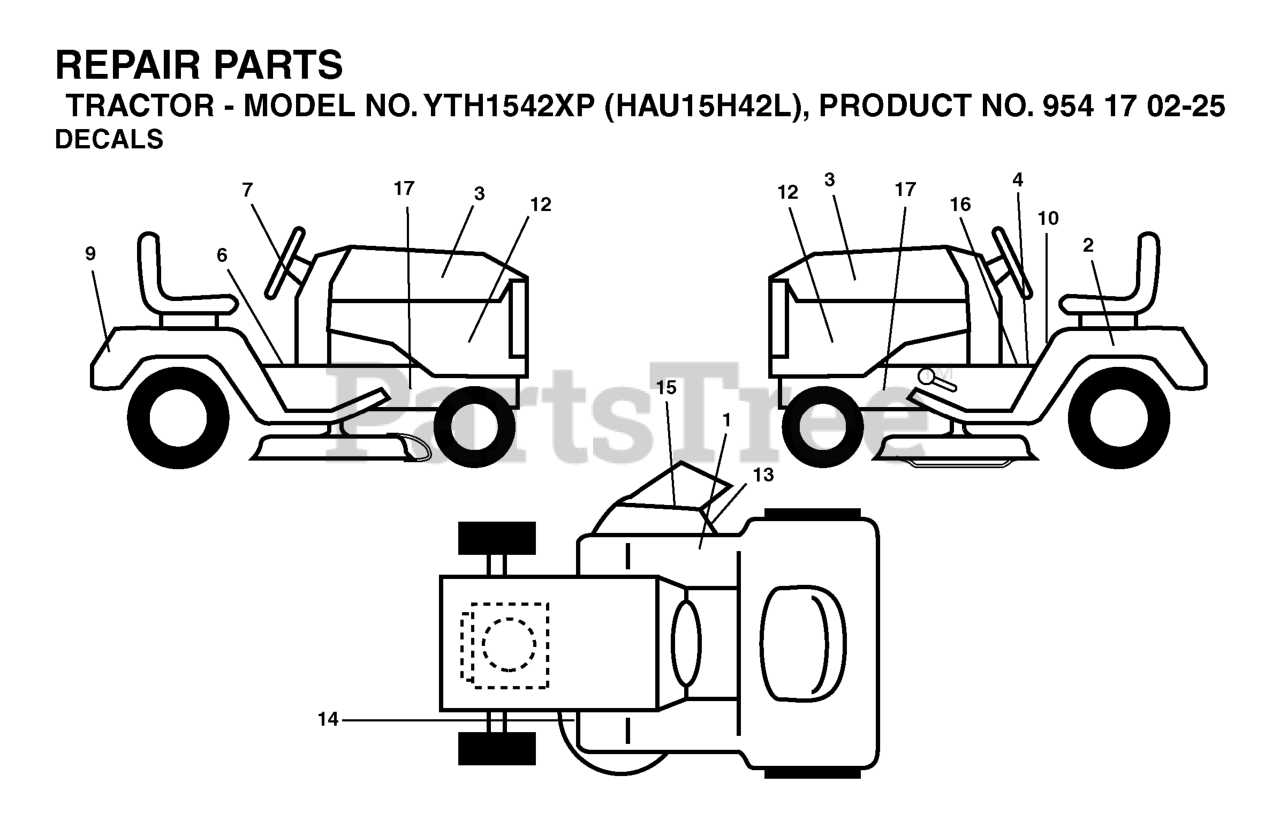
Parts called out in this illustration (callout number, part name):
1	DECAL
2	DECAL BTRY SYMBOLS
3	DECAL.HOOD.HUSQVARNA.INTERNATI
4	DECAL
6	DECAL PARK BRAKE
7	DECAL.STEERING.HUSQ.BLUE
10	DECAL READ OWNER'S MAN SYMS
13	DECAL.INTERNATIONL.CUTFINGER
14	DECAL V BELT SCHEMATIC
15	DECAL DECK "B" 42"
16	DECAL
